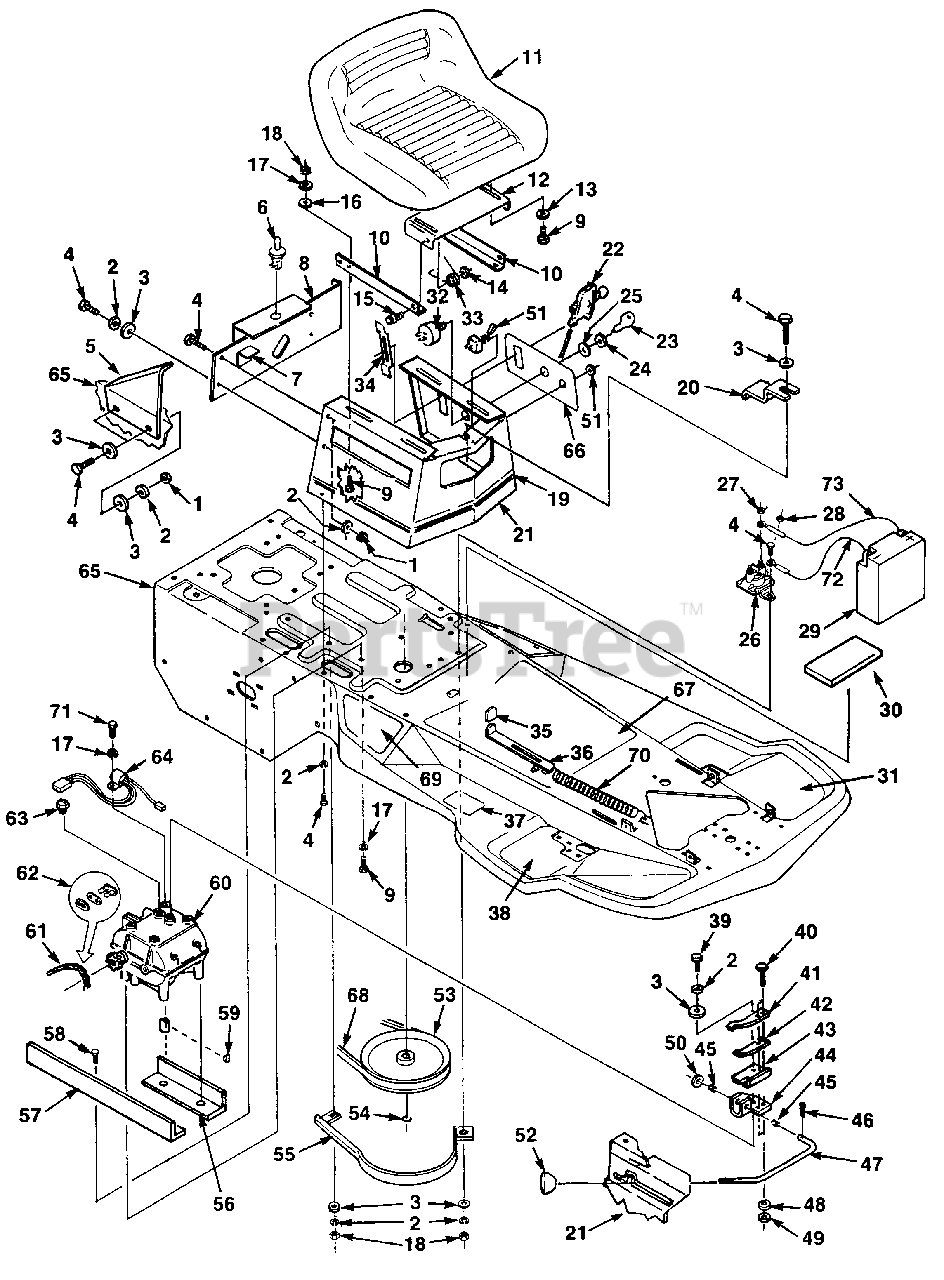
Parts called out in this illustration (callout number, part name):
1	NUT- Hex 1/4-20
2	WASHER- Lock 1/4
3	WASHER- Flat 1/4
4	BOLT- 1/4-20 x.625
5	BRACKET- Chain guard
6	SWITCH- Seat
8	PLATE- Reinforcement
9	BOLT- 5/16-18 x .750
10	SEAT RAIL
12	BRACKET- Seat
13	WASHER- Lock 5/16
14	NUT- Centerlock hex 5/16-18
15	BOLT- Shoulder 5/16-18 hex
16	WASHER- Plain 5/16
17	WASHER- Lock 5/16
18	NUT- 5/16-18 hex
19	DECAL- Seat support
20	BRACKET- Battery
21	TOWER- Seat
22	THROTTLE CONTROL & CABLE
23	KEY- Ignition
24	NUT- Ignition switch
25	WASHER- Ignition switch
26	SOLENOID- Switch
27	NUT
28	NUT
29	BATTERY
30	BATTERY PAD
31	FOOT REST (left hand)
32	IGNITION SWITCH
33	SPRING- Torsion
34	THROTTLE RETAINER
36	LATCHING- Parking brake
38	FOOT REST (right hand)
39	SCREW- Hex hd. 1/4-28 x.750
40	SCREW- Hex hd. sems #10-24 x.625
41	SPRING- Flat (shift yoke)
42	SPRING- Flat (shift yoke)
43	BRACKET- Yoke
44	SHIFT LEVER- Yoke
46	PIN- Cotter 1/8 x 3/4 plated
47	GEARSHIFT LEVER
48	WASHER- Lock #10
49	NUT- Hex 10-24
50	WASHER- Flat 3/8
51	SWITCH- P.T.O.
52	KNOB- Shift lever
53	TRANSMISSION PULLEY
54	RING- Snap
55	BELT GUARD- Transmission
56	ANGLE- Short
57	ANGLE- Long
58	BOLT- 1/4-20 x 3/4
59	KEY- Transmission
60	TRANSMISSION- Peerless Tecumseh
61	CHAIN- Drive
62	CONNECTING LINK- Chain
63	SWITCH- Neutral safety
64	NEUTRAL START SAFETY INTERLOCK
66	DECAL- Control manual
67	DECAL- Instruction
68	BELT- Transmission
69	DECAL- Shift pattern
71	SCREW- Thd. Form 5/16-18 3/4
72	CABLE- Ground
73	CABLE- Battery
